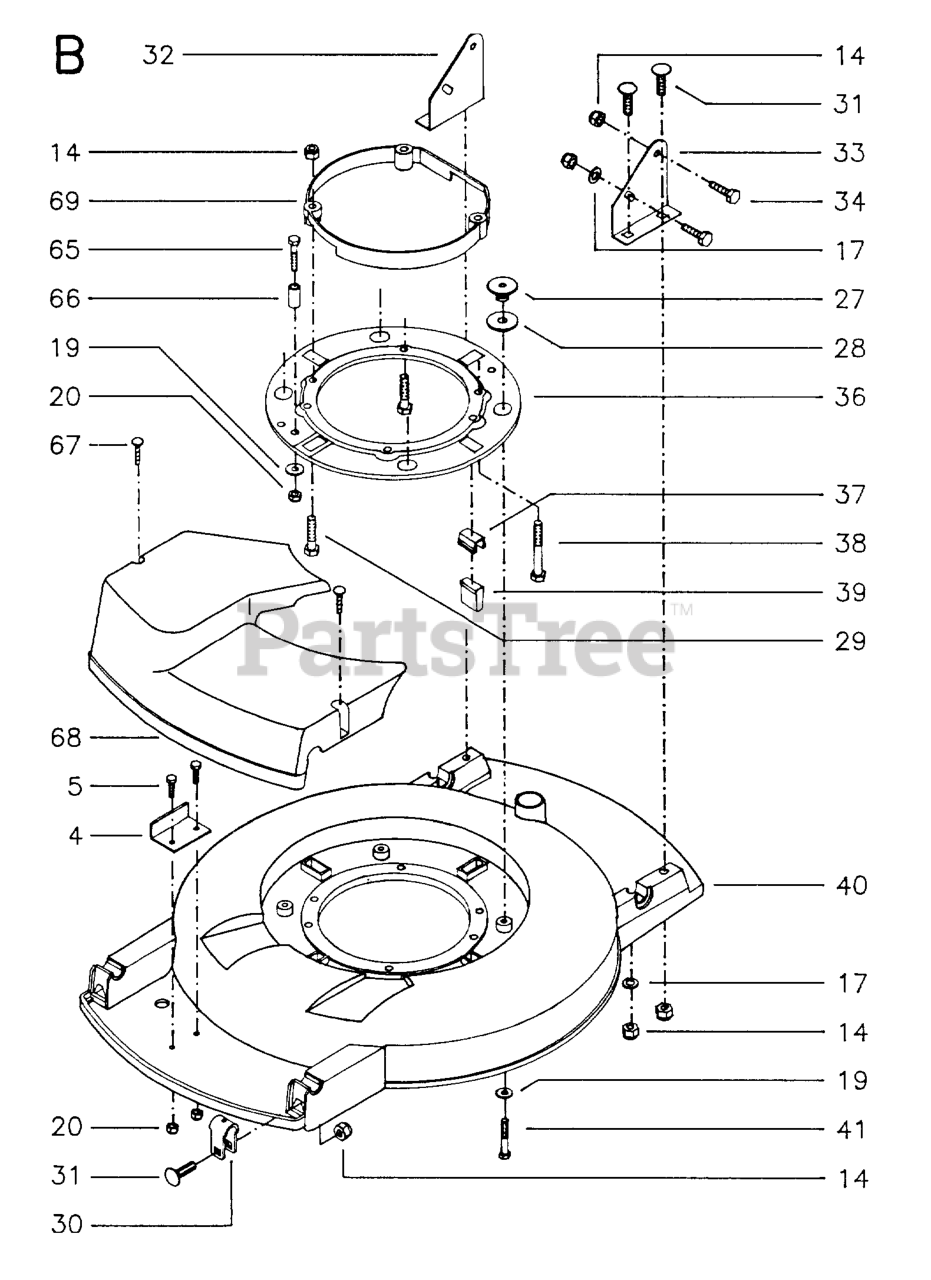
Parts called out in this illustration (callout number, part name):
5	Screw
14	LOCKNUT M8
17	WASHER - 15X7.3X1.6
20	LOCKNUT M6
30	BEARING HOLDER
32	HANDLE BRACKET
33	HANDLE BRACKET
34	BOLT - M8X16
65	BOLT FLANGE
